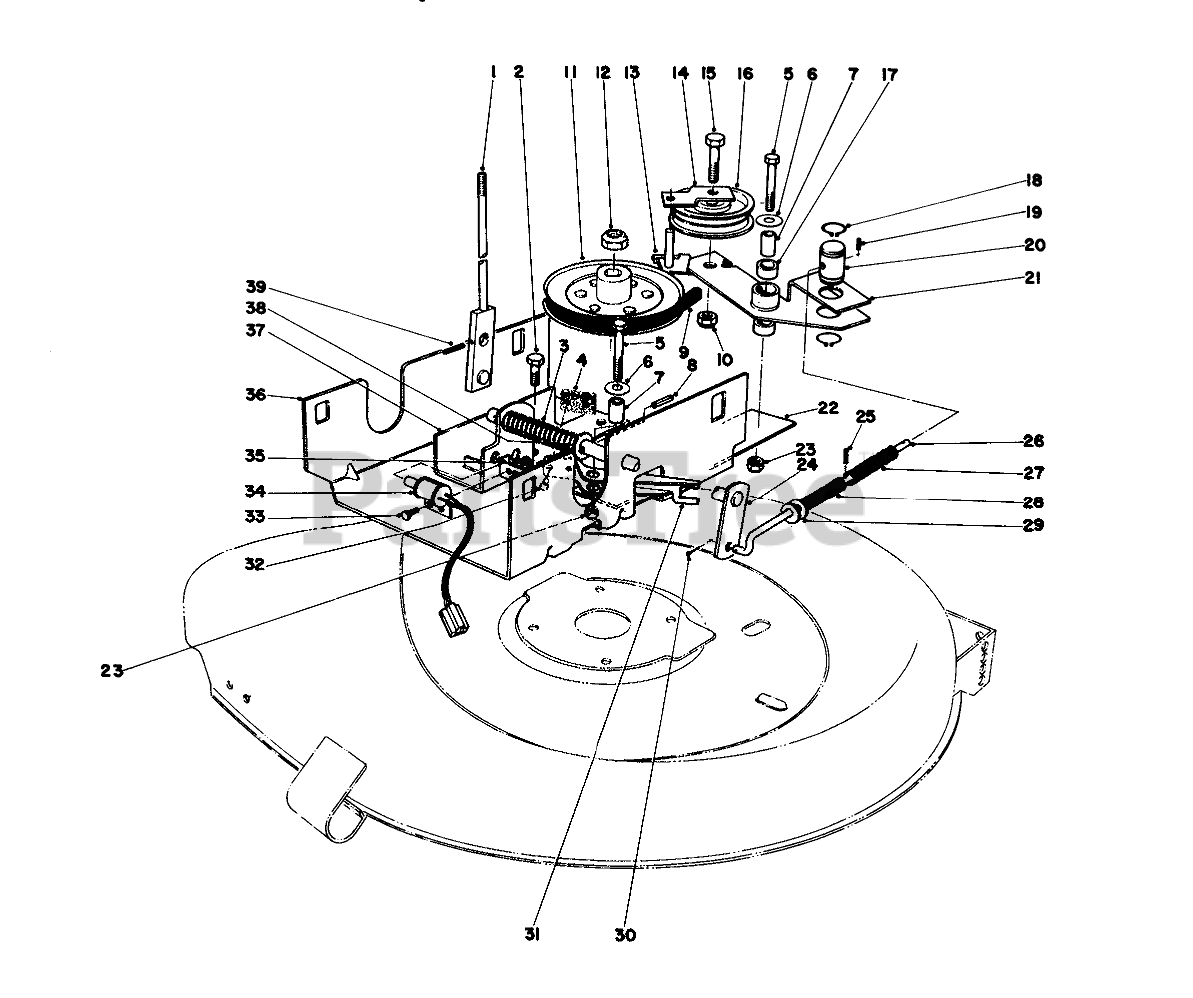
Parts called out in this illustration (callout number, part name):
1	Lever-Deck Engagement
2	SCREW-HH
3	COMP SPRING O
4	BLADE BRAKE LINING
5	SCREW-HH
6	WASHER-PLAIN
7	PIVOT SPACER
8	PIN-SPRING
9	V-BELT
10	NUT-LOCK, SIDE
11	DECK PULLEY R
13	Belt Retainer
14	BELT RETAINER UPPER
15	SCREW-HH
16	Flat Idler
17	Bushing
18	RING-RETAINING
19	PIN-ROLL
20	Pin-Pivot
21	Idler Arm (Incl. Ref. #17)
22	Bracket Idler Mounting
23	NUT-LOCK, CONE
24	Linkage
25	PIN-SPRING
26	BLADE ENGAGE ROD
27	Spring Deck Idler
28	Spring Deck Brake
29	WASHER
30	PIN-COTTER
31	Blade Brake (Incl. Ref. #4 & 32)
32	Rivet
34	DECK INTERLOCK SWITCH
35	NUT-KEPS
36	CHANNEL HT ADJ R
37	Mounting Bracket Blade
38	WASHER-FLAT
39	PIN-SPIRAL
